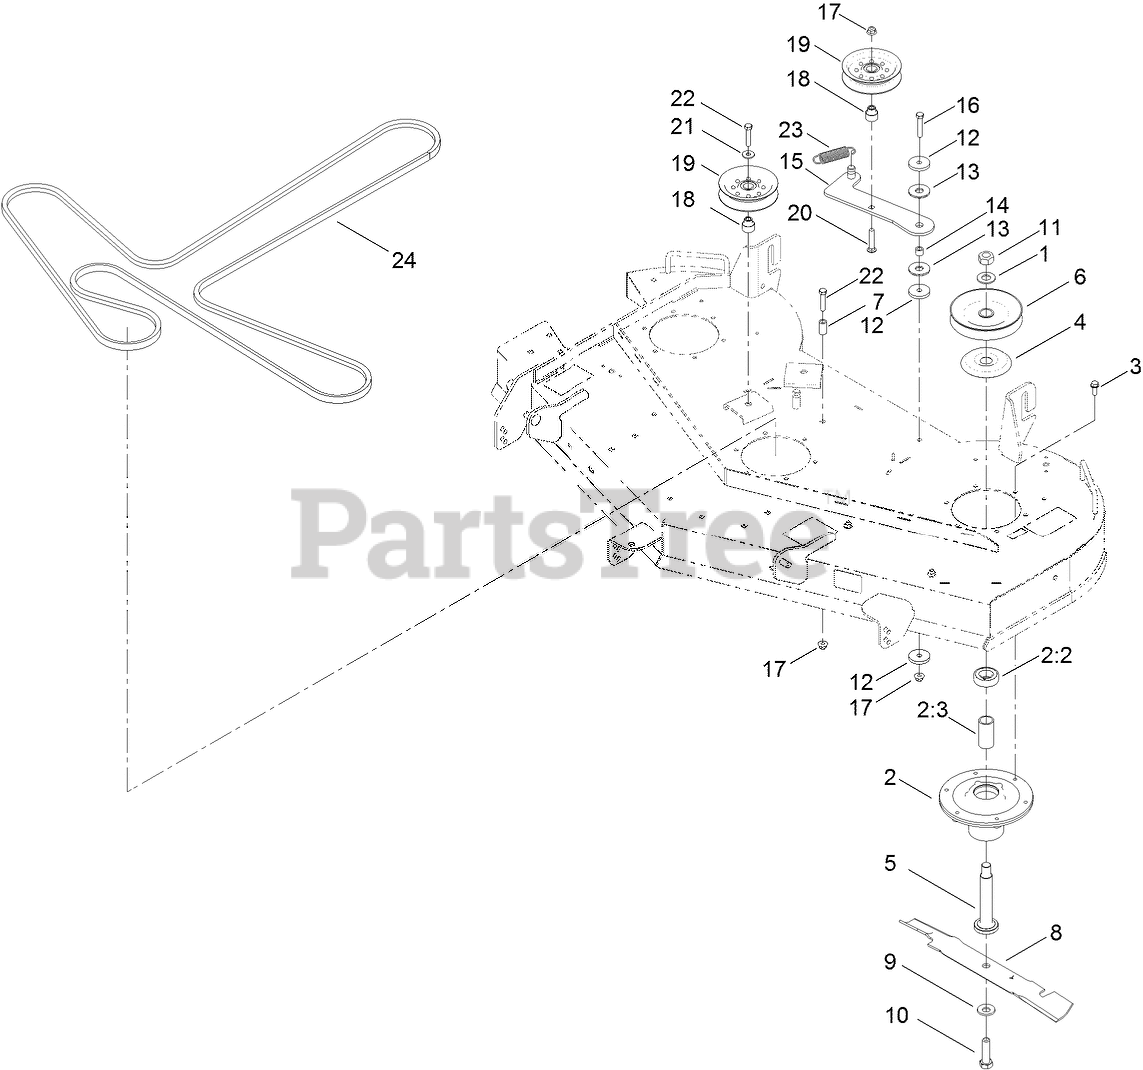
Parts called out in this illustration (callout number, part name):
1	WASHER
2	SPINDLE ASM
2:2	BEARING-BALL
2:3	SPACER-BEARING
3	SCREW-TAPTITE
4	SHIELD-BEARING
5	SHAFT-SPINDLE
6	PULLEY
7	SPACER
8	BLADE-MULCH, 18.75 INCH
9	WASHER-BELLEVILLE
10	SCREW-BLADE
11	NUT-HEX
12	WASHER-PLAIN
13	WASHER-FRICTION, COMPOSITE
14	BUSHING-LEVER, LIFT
15	ARM-IDLER
16	SCREW-HH
17	NUT-HF, NI
18	BUSHING-IDLER
19	PULLEY-IDLER
20	SCREW-CARR
21	WASHER-HARDENED
22	SCREW-HH
23	SPRING-EXTENSION
24	V-BELT
